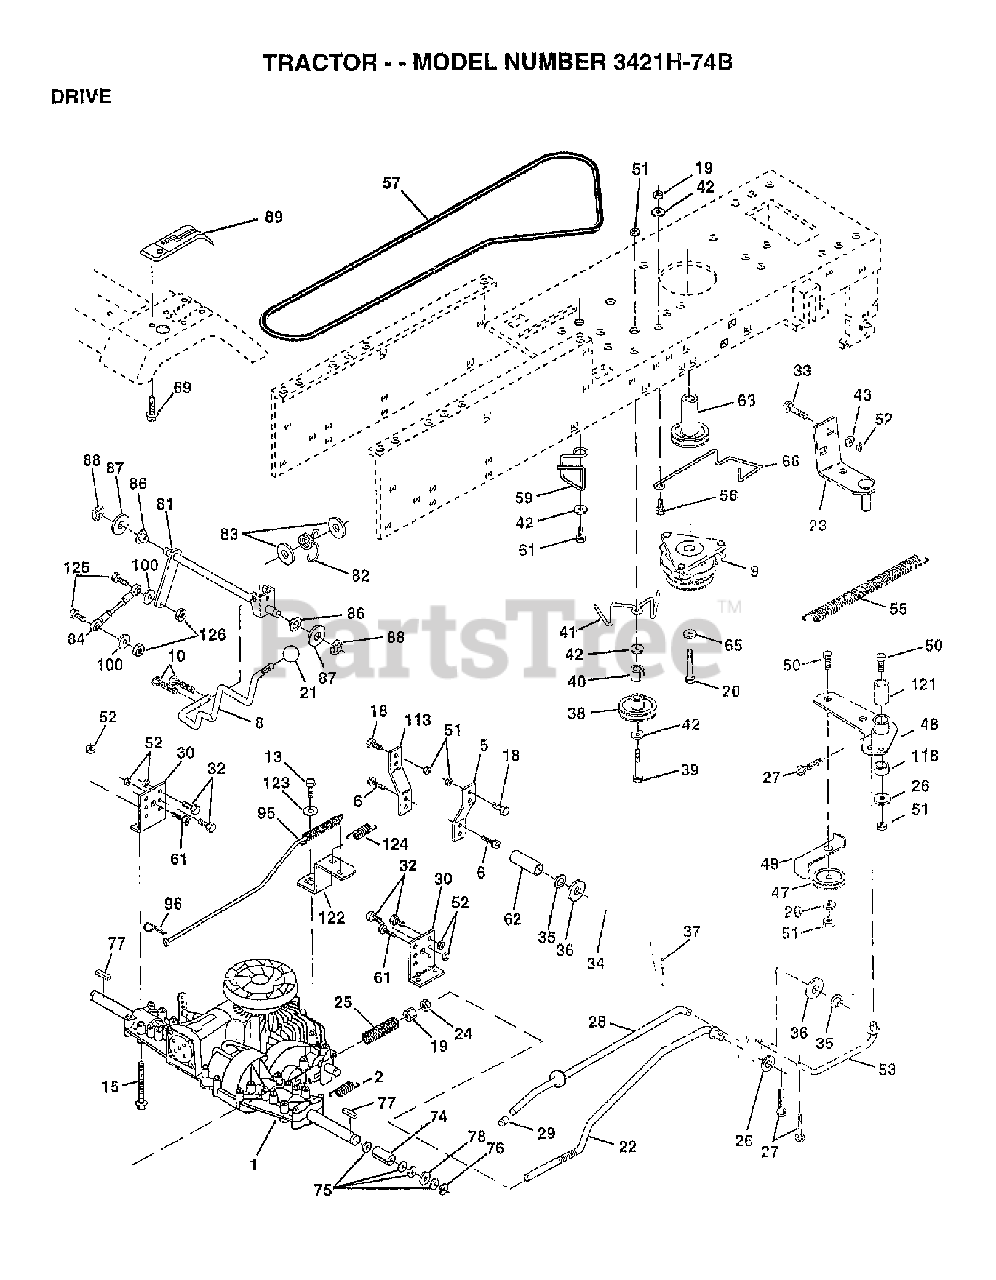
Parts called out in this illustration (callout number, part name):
1	Poulan TBD
2	SPRING T
5	STRAP TORQUE
6	Screw, Lt
8	ROD SHIFT
10	PIN COTTER
13	BOLT LT
15	BOLT HEX 5/16-18 GR 5
18	BOLT
19	NUT
20	BOLT
21	KNOB T (1/2-HOLE)
22	ROD BRAKE
23	BRACKET ASM MTG
24	NUT
25	SPRING ROD LT
27	COTTER PIN
29	PLUNGER CAP
30	BRACKET TRANSAXLE
32	BOLT
33	BOLT
34	SHAFT, FOOT PEDAL
35	BEARING.NYLON
36	WASHER LT
37	Drive Pin, 3/16 X 1"
38	FLAT IDLER PULLEY
40	SPACER T
42	WASHER
43	WASHER T
47	Idler Pulley
48	BELLCRANK ASSEMBLY
49	RETAIN BELT
50	Hex Bolt
51	LOCKNUT
52	LOCKNUT
55	SPRING, RETURN LT
57	Belt
62	PEDAL COVER
63	PULLEY CLU ELEC
65	LOCKWASHER
66	KEEPER BELT ENGINE
69	SCREW.HI-LO.CONSOLE
74	SPACER, AXLE PVST
76	E-RING LT
77	SQUARE KEY
81	SHAFT ASM CROSS HYDRO
82	SPRING,TORSION
83	WASHER
84	ROD, TIE PVST 20"
86	BUSHING.STEERING.ROD
87	WASHER D
88	KLIP RING
95	ROD ASM BYPASS PVST
96	RETAINER M
100	WASHER M
113	STRAP TORQUE LH LT
121	NYLINER CLUTCHING
122	PLATE BYPASS PVST
124	RETURN SPRING
125	BOLT.FIN.HEX.5/16-18UNC X 1.00
126	Lock Nut
